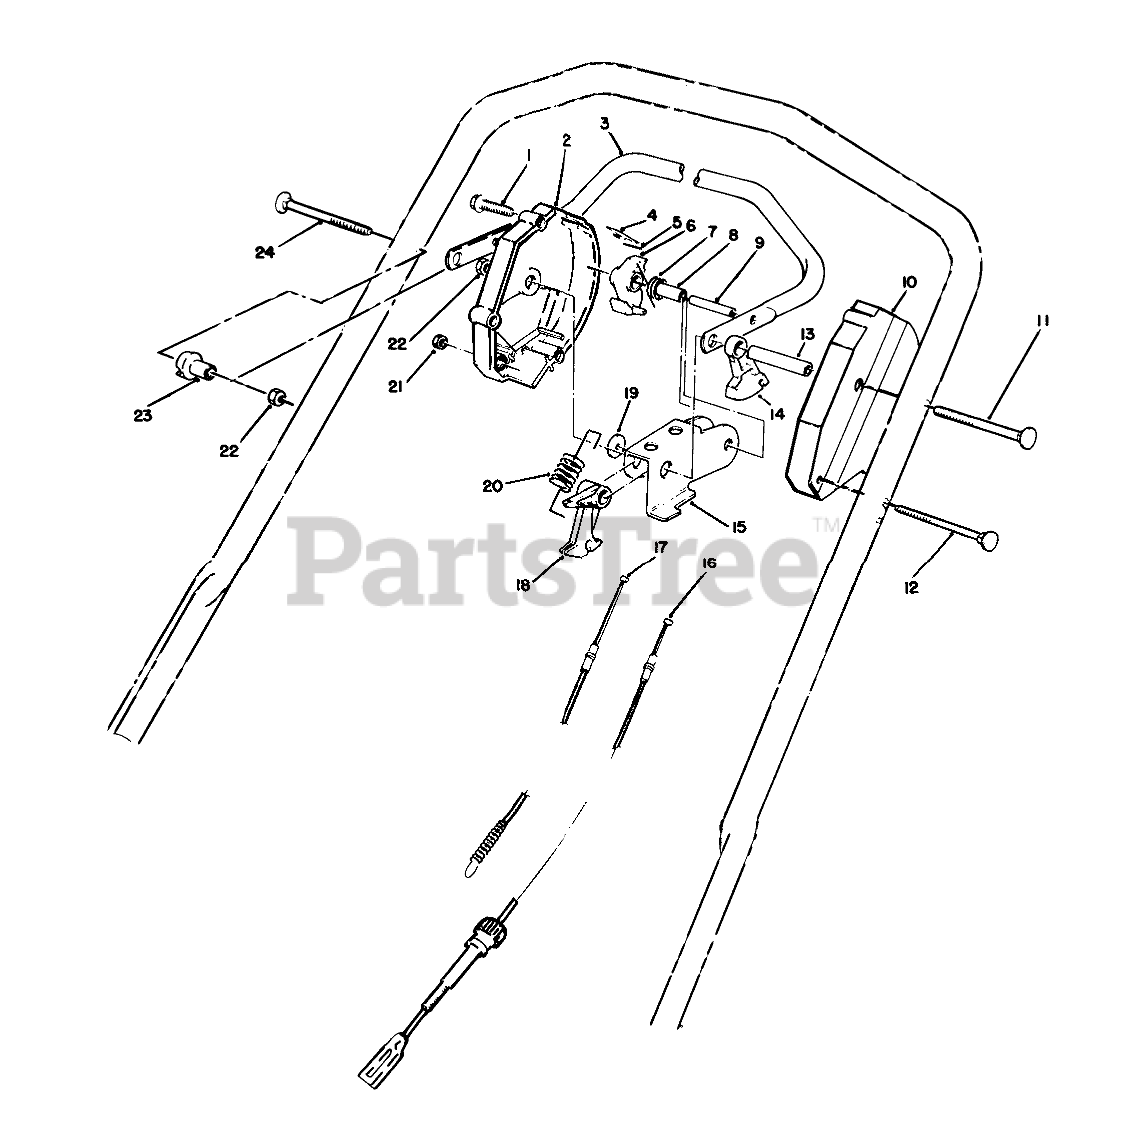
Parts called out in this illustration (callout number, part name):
1	SCREW-HWHTF
2	Housing-Control
3	Bar-Control
4	SPRING-LEAF
5	PIN-INSERT
6	HOOK-CONTROL
7	SPRING-TORSION
8	SPACER
9	PIN-ROLL, SLOTTED
10	HOUSING-CONTROL, LH
11	5/16-18 X 3 HNDLE SCREW
12	HANDLE SCREW
13	TUBING-SPACER
14	LEVER-TRACTION
15	ROCKER
16	TRACTION CABLE
17	Cable-Clutch
18	LEVER-CABLE
19	PLASTIC WASHER
20	DETENT SPRING
21	NUT-HEX
22	NUT-LOCK, NI
23	SPACER-SUPPORT
24	5/16-18 X 2 HNDLE SCREW
